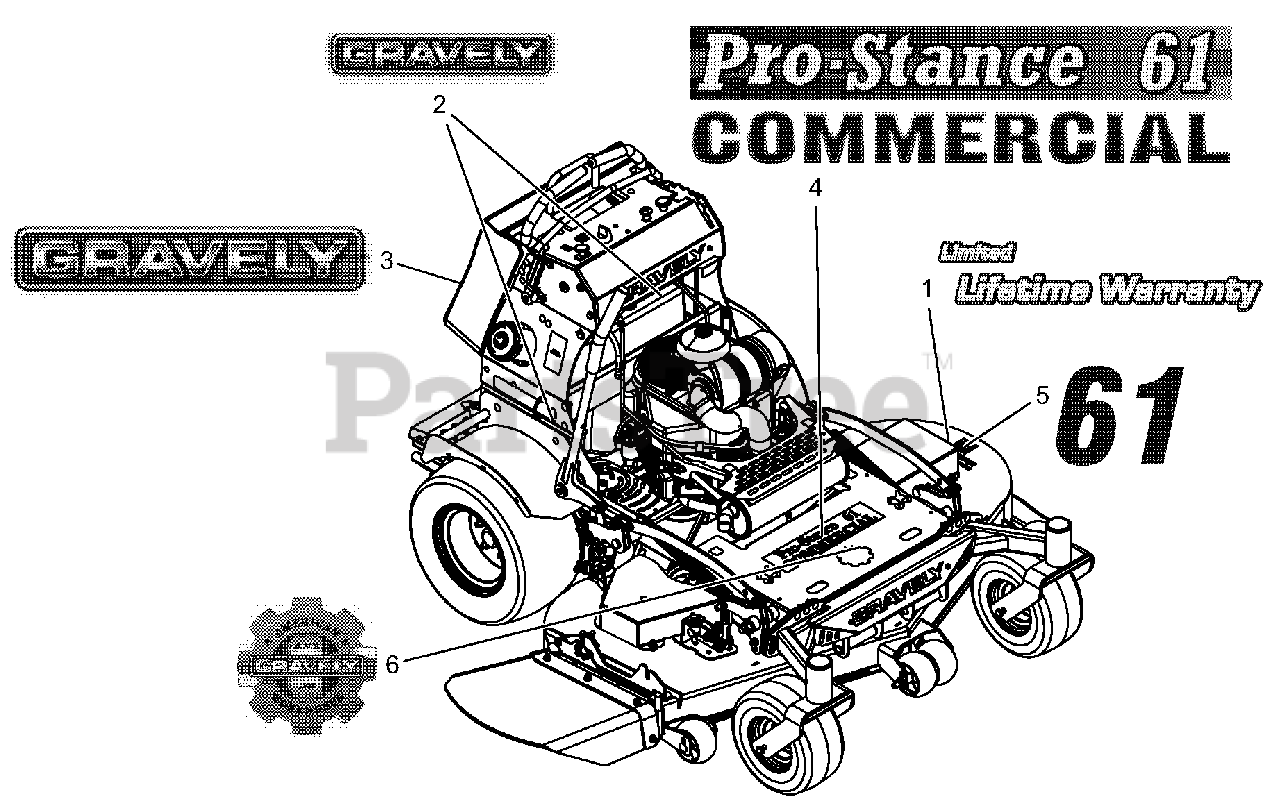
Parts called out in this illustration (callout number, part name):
1	DECAL, LIMITED LIFETIME WARRANTY REV
2	DECAL, 9.5" GRAVELY LOGO
3	DECAL, FUEL TANK-GRAVELY
4	DECAL, PROSTANCE 61"
5	DECAL, 61"
6	DECAL, GRAVELY HERITAGE-LARGE
